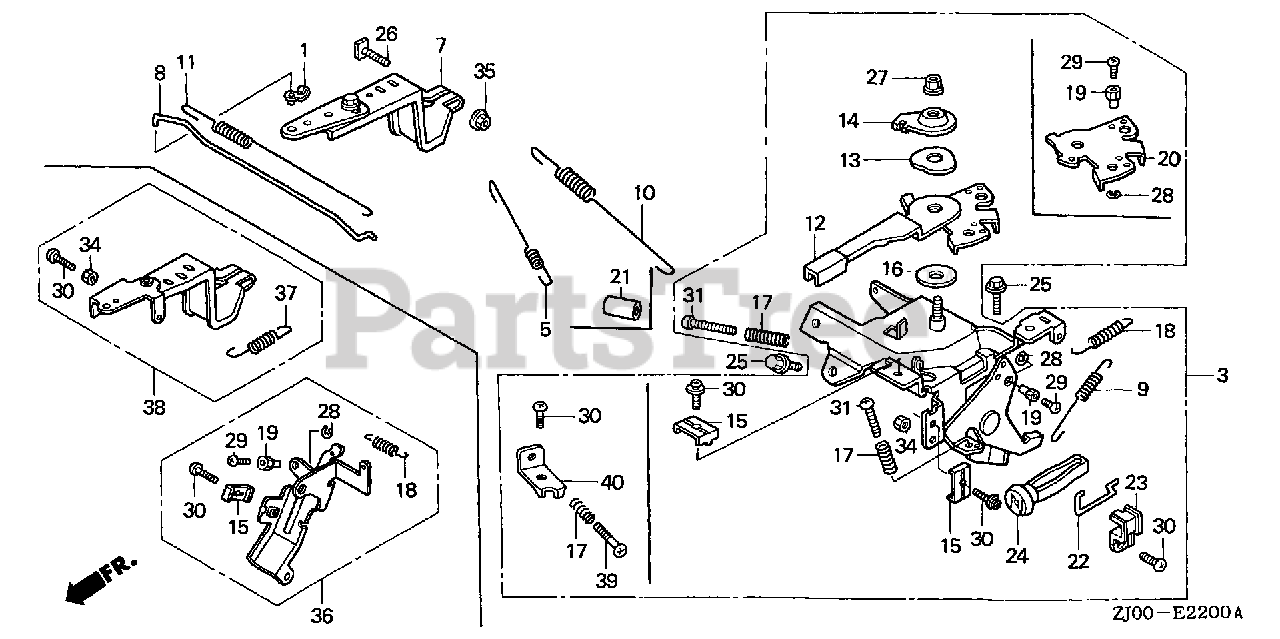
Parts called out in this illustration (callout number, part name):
1	JOINT, ROD
3	CONTROL ASSY.
8	ROD, GOVERNOR
9	SPRING, GOVERNOR
10	SPRING, GOVERNOR
11	SPRING, THROTTLE RETURN
13	SPRING, LEVER
14	WASHER, CONTROL LEVER
15	HOLDER, CABLE
16	SPACER, CONTROL LEVER
17	SPRING, CONTROL ADJUSTING
18	SPRING, CABLE RETURN
19	HOLDER, WIRE
22	ROD, CHOKE KNOB
23	HOLDER, CHOKE KNOB
24	KNOB, CHOKE
25	BOLT, FLANGE (6X12) (CT200)
26	BOLT, GOVERNOR ARM
27	NUT, SELF-LOCK (6MM)
28	CIRCLIP (5MM)
29	SCREW, PAN (4X6)
30	SCREW, PAN (5X12)
30	SCREW, PAN (5X16)
31	SCREW, PAN (5X25)
34	NUT, HEX. (5MM)
35	NUT, FLANGE (6MM)
36	STAY ASSY., AUTO THROTTLE
37	SPRING, RETURN
38	ARM, GOVERNOR (NOT AVAILABLE)
39	SCREW, PAN (5X28)
40	STOPPER, CONTROL LEVER
